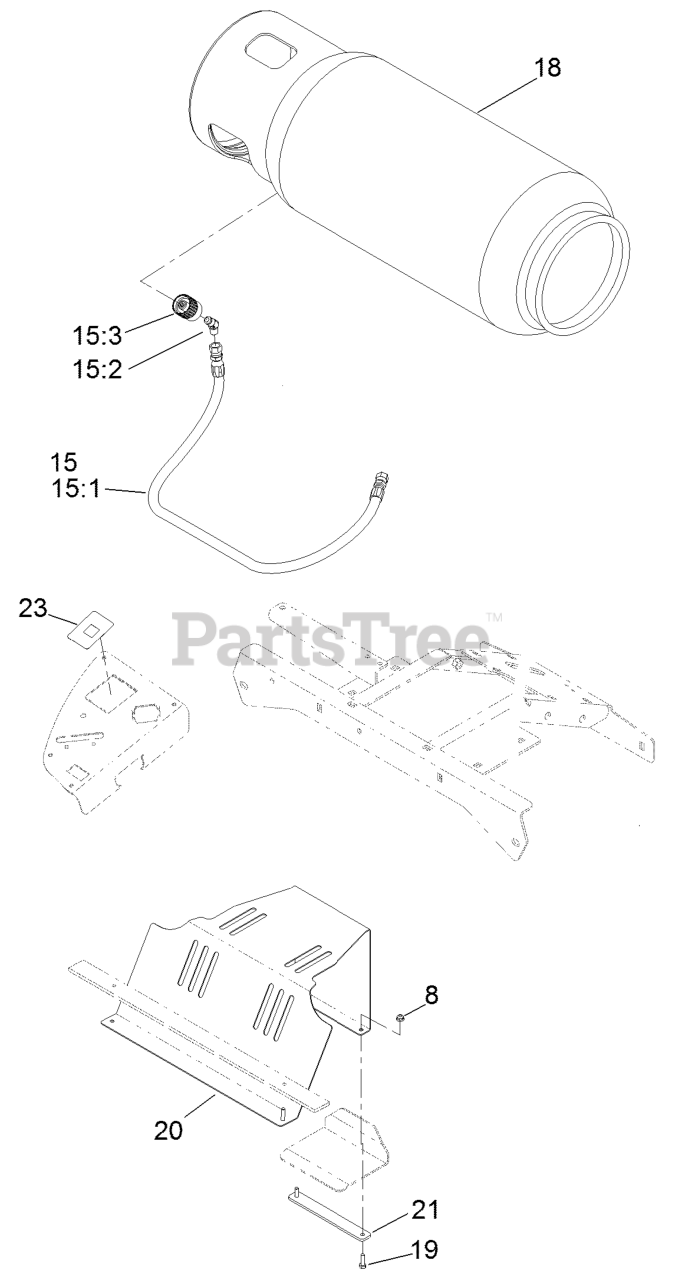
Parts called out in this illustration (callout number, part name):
15:1	LPG FUEL HOSE ASM
15:2	ELBOW-45 DEG
15:3	CONNECTOR-LPG TANK, LH TH
19	SCREW-HH
20	SHEILD-FAN
23	DECAL-METER, HOUR
